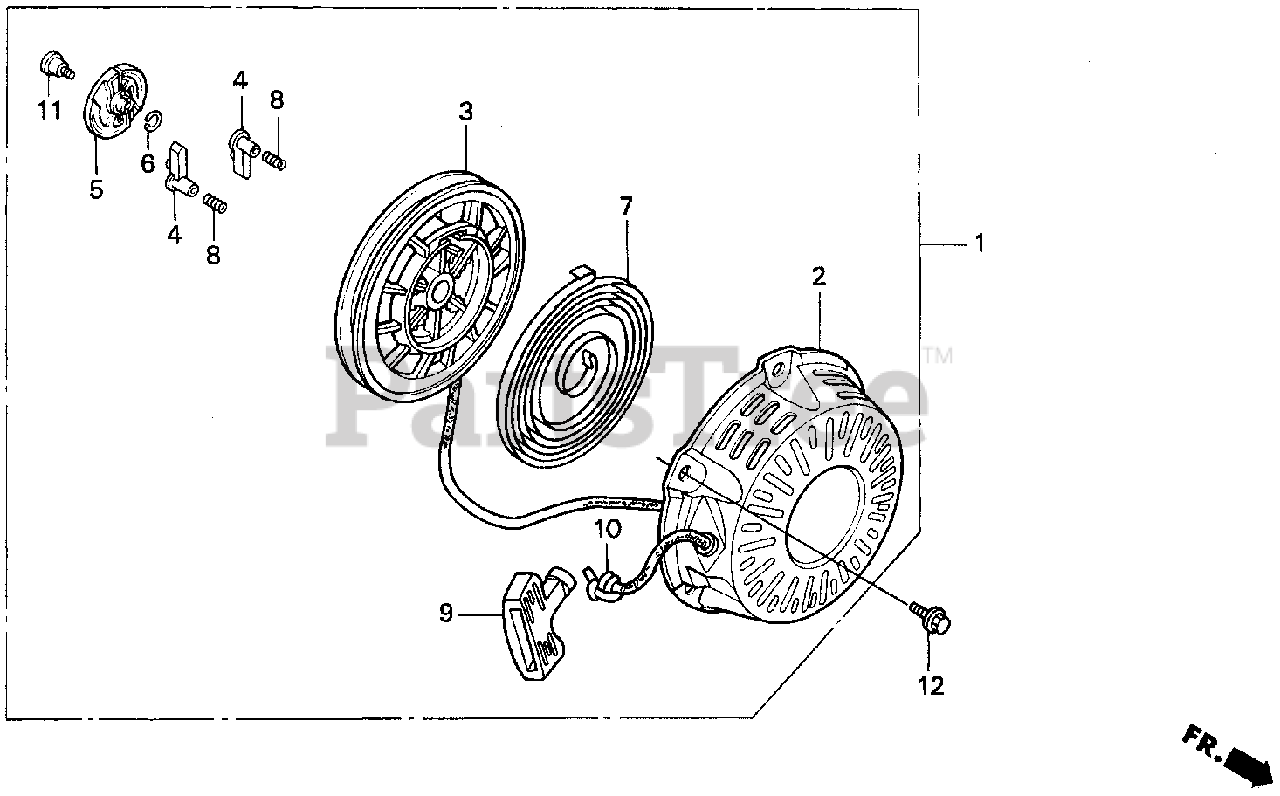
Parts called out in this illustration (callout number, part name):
1	STARTER ASSY., RECOIL *R8* (BRIGHT RED)
1	STARTER ASSY., RECOIL *NH1* (BLACK)
2	CASE, RECOIL STARTER *R8* (BRIGHT RED)
2	CASE, RECOIL STARTER *NH1* (BLACK)
3	REEL, RECOIL STARTER
4	RATCHET, STARTER
5	GUIDE, RATCHET
6	SPRING, FRICTION
7	SPRING, RECOIL STARTER
8	SPRING, RETURN
9	KNOB, RECOIL STARTER
10	ROPE, RECOIL STARTER (NA USE ALT:08550-ZG921-11)
11	SCREW, SETTING
12	BOLT, FLANGE (6X10)
